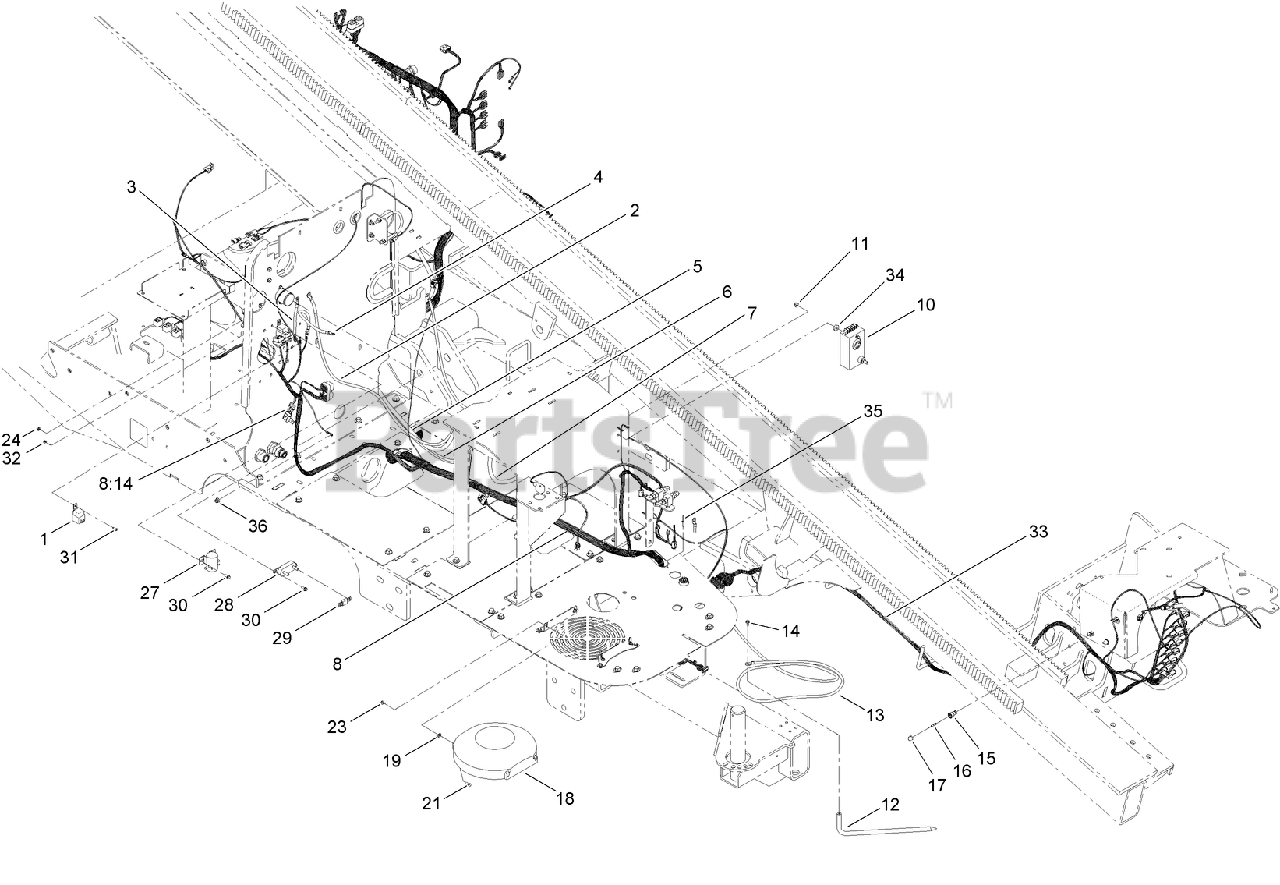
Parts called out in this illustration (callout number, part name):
1	RELAY
2	CABLE-BATTERY, POSITIVE
3	CABLE-BATTERY, POSITIVE
4	CABLE-BATTERY, POSITIVE
5	CABLE-BATTERY, POSITIVE
6	CABLE-BATTERY, NEGATIVE
7	CABLE-BATTERY, NEGATIVE
8	HARNESS-WIRE, MAIN
8:14	FUSE-BLADE, 10 AMP
11	NUT-HF, NI
12	BAR-STAKE, GROUND
13	CABLE-ALERT, STRIKE
14	SCREW-HHF
15	TYPE T-2 SOCKET ASM
16	LAMP-LED
17	LENS-DOME, FLUTED GREEN (TYPE T2)
18	FAN-ELECTRIC
19	WASHER-FLAT
21	SCREW-HH
23	NUT-HF
24	NUT-FLANGE, NI
27	SOLENOID-RELAY 12V, 300A
28	HOLDER-FUSE
29	FUSE-100A
30	SCREW-HHF
31	SCREW-HSBH
32	NUT-HF
33	HARNESS-WIRE, THRUST FRAME
34	SPACER-PIN, MOUNTING
35	RIVET-POP
36	NUT-LOCK, HHF
